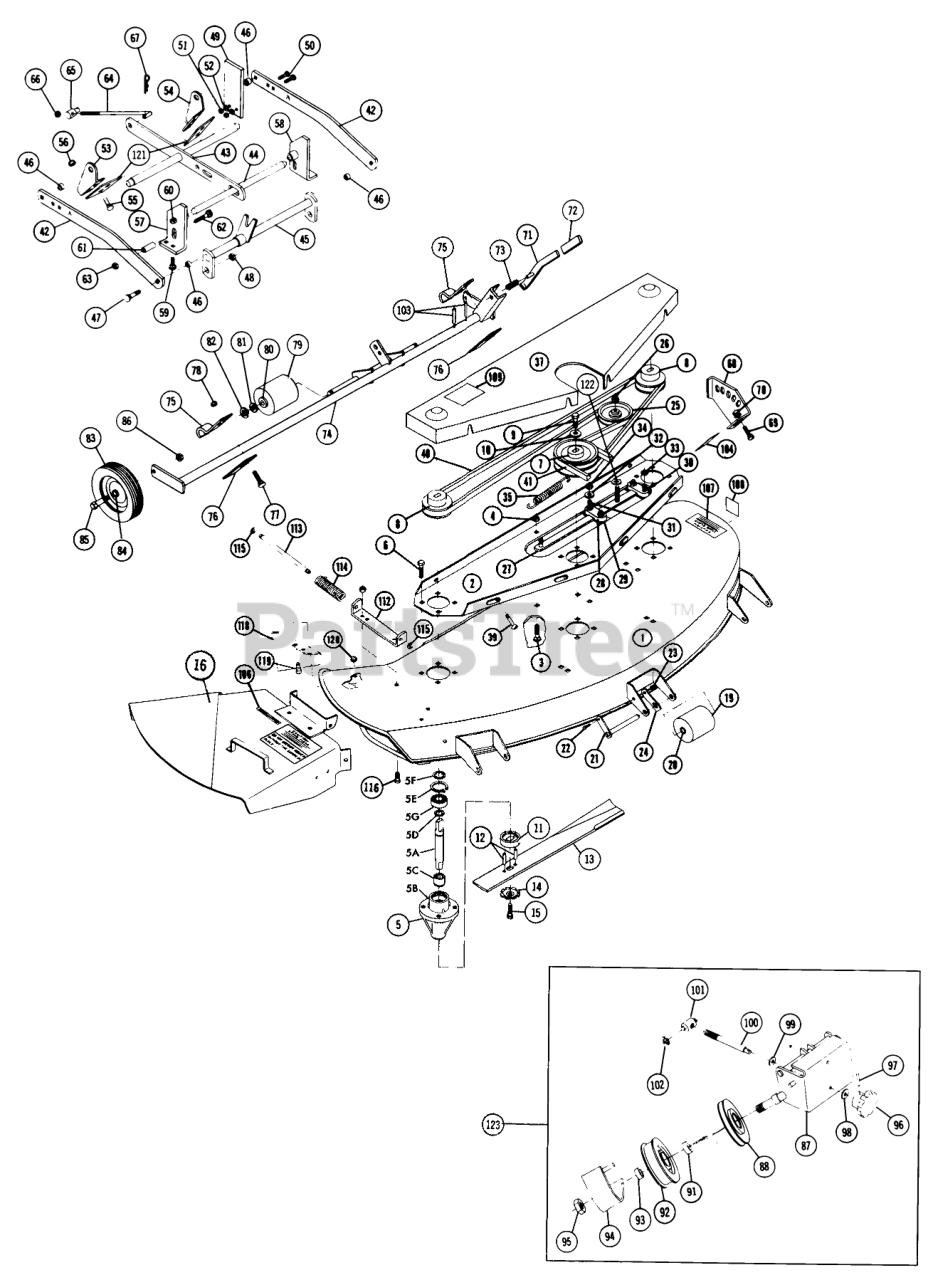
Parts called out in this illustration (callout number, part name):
1	Deck
1	Deck-42"
2	Support
3	Bolt-Carriage
4	NUT
5	Spindle Assy.
5A	SHAFT SPINDLE
5B	HOUSING SPINDLE
5C	NEEDLE BEARING
5D	Snap Ring
5E	INT SNAP RING
5F	WASHER-THRUST
5G	BEARING
6	Bolt
7	Pulley-Center
7	Center Pulley
8	Pulley-Right & Left
8	End Pulley
9	Bolt
10	WASHER
11	Cup-Spindle
12	SPIROL ROLL PIN
13	BLADE KIT 48 LF
13	BLADE KIT 42 LF
14	WASHER
15	Bolt
16	Chute Extension
17	SCREW
18	Nut
19	Roller
20	BUSHING
21	Roller Shaft
22	H H C S
23	Nut
24	SPRING ROLLER STOP
25	Pulley-Idler
25	Idler Pulley
26	Nut
27	ASSY BAR IDLER SUPPO
28	Side Block
29	SLIDE
30	Bolt-Carriage
31	Bolt-Carriage
32	WASHER 5/16 SAE
33	Nut
34	Nut
35	SPRING R
36	ANGLE
37	Cover
37	Belt Cover
38	Bolt
39	Screw
40	V-BELT
40	V BELT
41	V-BELT
42	Bar Draft
43	Leveler Ass-y.
44	Front Shaft
45	Hitch
46	SPACER
47	Bolt
48	LOCKNUT-FLANGE
49	BUMPER
50	Bolt-Carriage
51	Nut
52	Collar
53	Bracket-R.H.
53	Bracket-Rt. Rear
54	Bracket-L.H.
54	Bracket-L.H. Rear
55	Bolt
56	Nut
57	Bracket-R.H.
58	Bracket-L.H.
59	Bolt-Carriage
60	Nut
61	SPACER-BEARING
62	CARRIAGE BOLT -4
63	Nut
64	ROD-LEVELER
64	ROD-LIFT
65	TRUNNION-LIFT
66	NUT
67	Hairpin
68	LH QUADRANT R
68	Quadrant
69	Bolt
70	NUT
71	Lever
71	LEVER ASSY R
73	SPRING-COMPRESSION
74	Gage Wheel Support
74	Support Ass-y. Gage Wheel
75	Machine Bolt
76	Bar
77	Bolt
78	NUT
79	Roller
80	BUSHING
81	Washer
82	E Ring
83	Wheel
84	BEARING
85	BOLT-SHOULDER
86	Nut
87	Front Support
88	Pulley-V
91	SPACER
92	PULLEY-FLAT IDLER
93	SPACER-OUTER
94	Belt Cover
95	Nut 3/4-16 MF
96	KNOB-ADJUSTMENT
97	PIN-ROLL
98	Washer
99	Washer
100	ROD ADJ
101	TRUNNION-DOUBLE
102	E Ring-3/8
103	PIN-SPIROL
104	Decal Height Adjustment
105	Decal-Caution
106	Decal Mower Width
107	Decal
108	DECAL-WHEEL HORSE
109	Decal-Belt Diagram
110	Bracket
111	Bolt
112	Deck Bracket
114	Spring
115	Lock Rod
116	Bolt
118	Chute Guard
119	Bolt
120	Nut
121	PLATE
122	Washer
123	ASM-SUPPORT,IDLER
